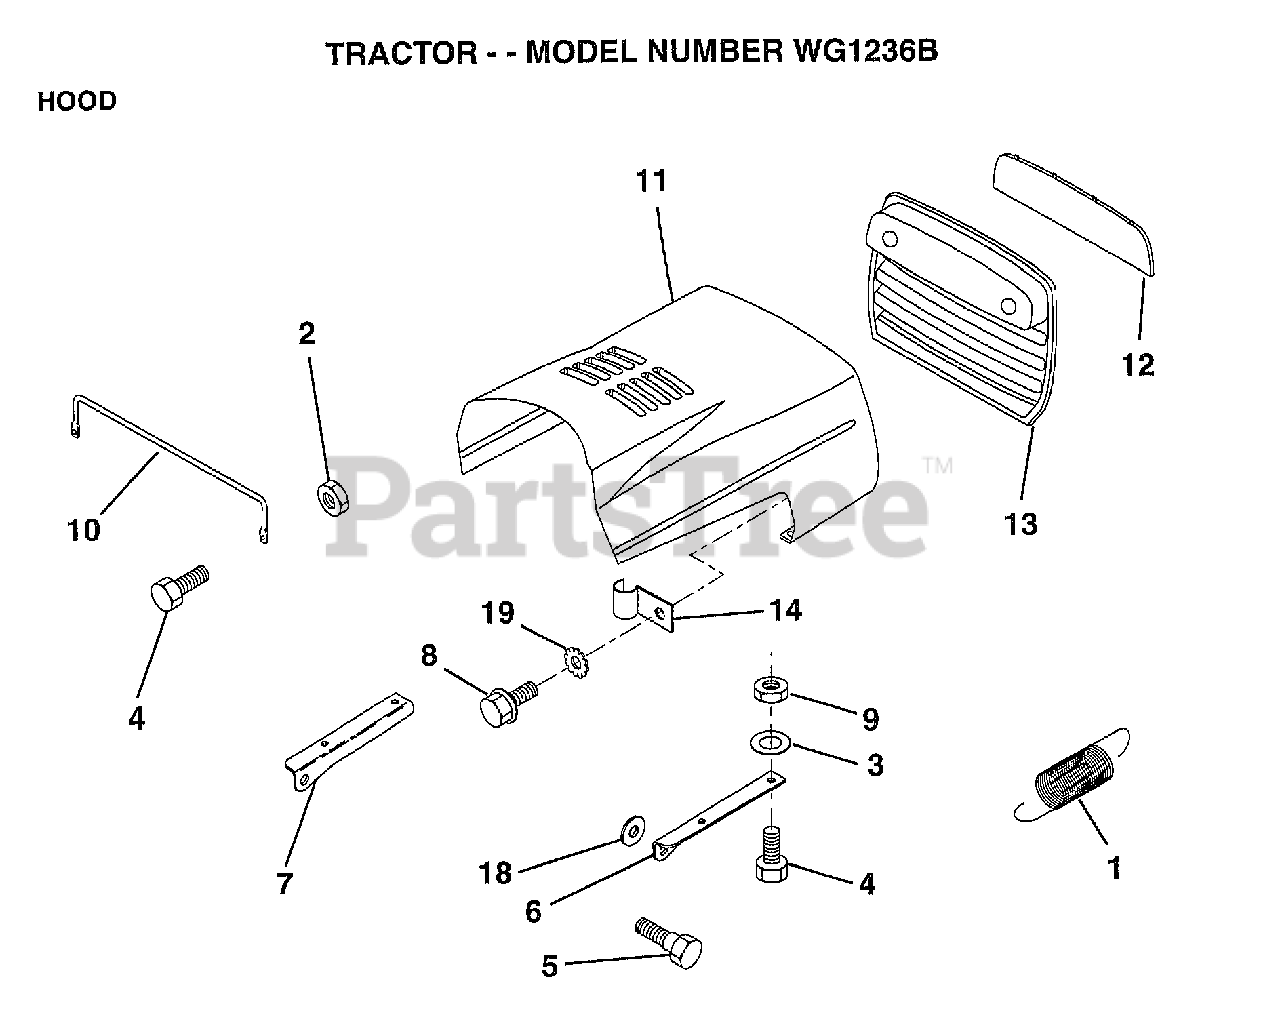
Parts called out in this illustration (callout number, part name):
1	EXT SPRING
2	NUT HXKEP 1/4X20
3	WASHER
5	BOLT.SHLD.5/16-18
6	BRKT HOOD RH
7	BRKT HOOD LH
8	SCREW SLTD HXHD
9	NUT
10	"BRACE,HOOD"
11	HOOD.IMPREG.MS550
12	LENS
13	GRILL
14	CLIP T
18	WASHER
19	LOCKWASHER GT
